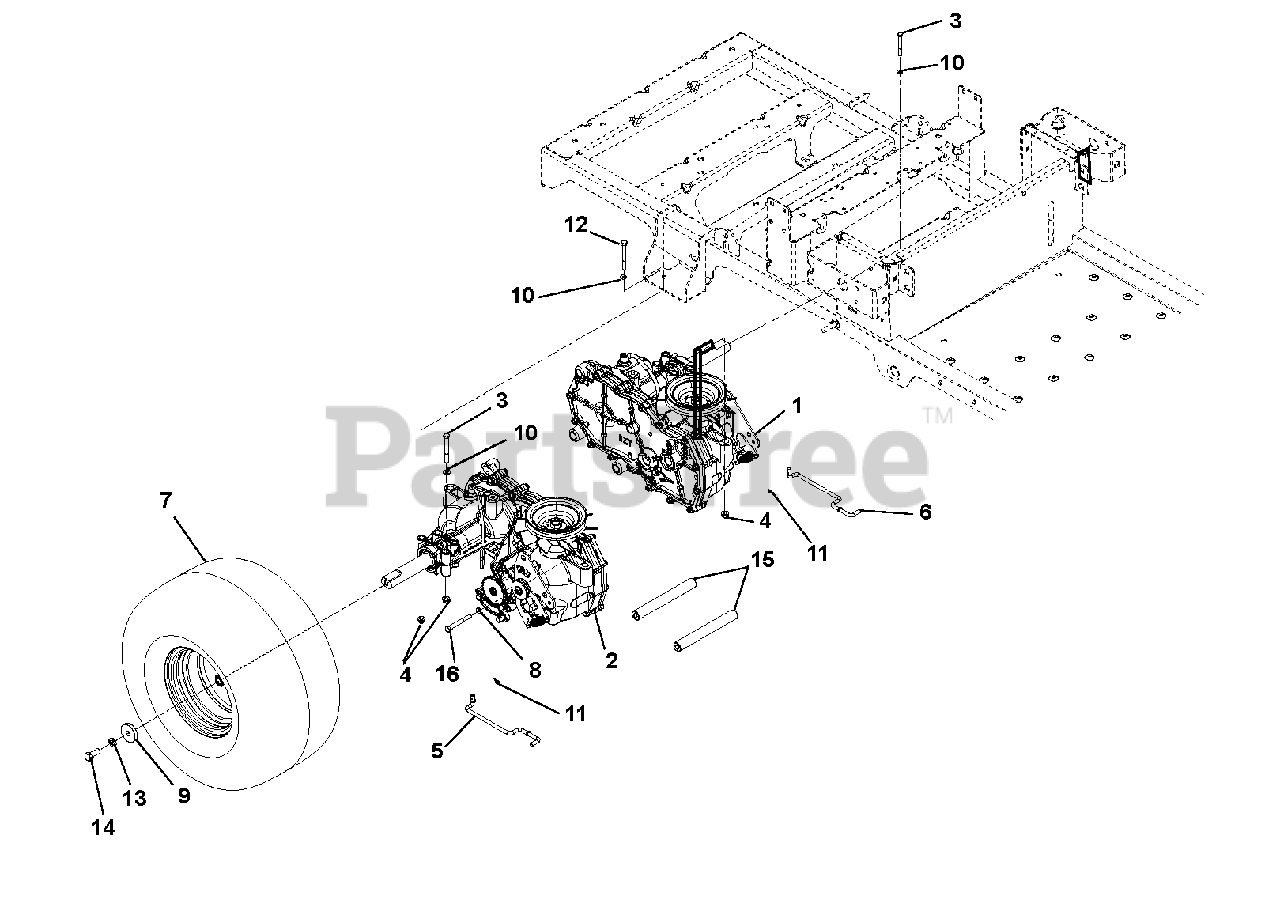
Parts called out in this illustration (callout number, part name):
1	Transaxle, Left Hand EZT D-Shaft (915327)
1	Transaxle, Left Hand EZT D-Shaft Long (915328)
2	Transaxle, Right Hand EZT D-Shaft (915327)
2	Transaxle, Right Hand EZT D-Shaft Long (915328)
3	Bolt, Hex .31-18 x 2.25
4	Nut 5/16-18 Flange Nyloc
5	Dump Valve, Right Hand
6	Dump Valve, Left Hand
7	Tire Assembly 18 x 6.5-8 2 Ply DSHAFT (915327)
7	Tire/Wheel Assembly, 18 x 8.5-8 Center (915328)
8	Washer, Flat Steel .406 x 1.00 x .188
9	Washer, Flat Steel .406 x 1.50 x .245
10	Washer, Flat Steel .38 x .875 x .083
11	Pin, Hair, Internal .06 x .18 x .77
12	Bolt, Hex .31-18 x 2.75
13	Washer, Locking .38 x .094 Regular
14	Bolt, Hex .38-16 x 1.00 YWZC EP30
15	Shaft, Transaxle Brace
16	BOLT, HEX .38-16 X 2.50
